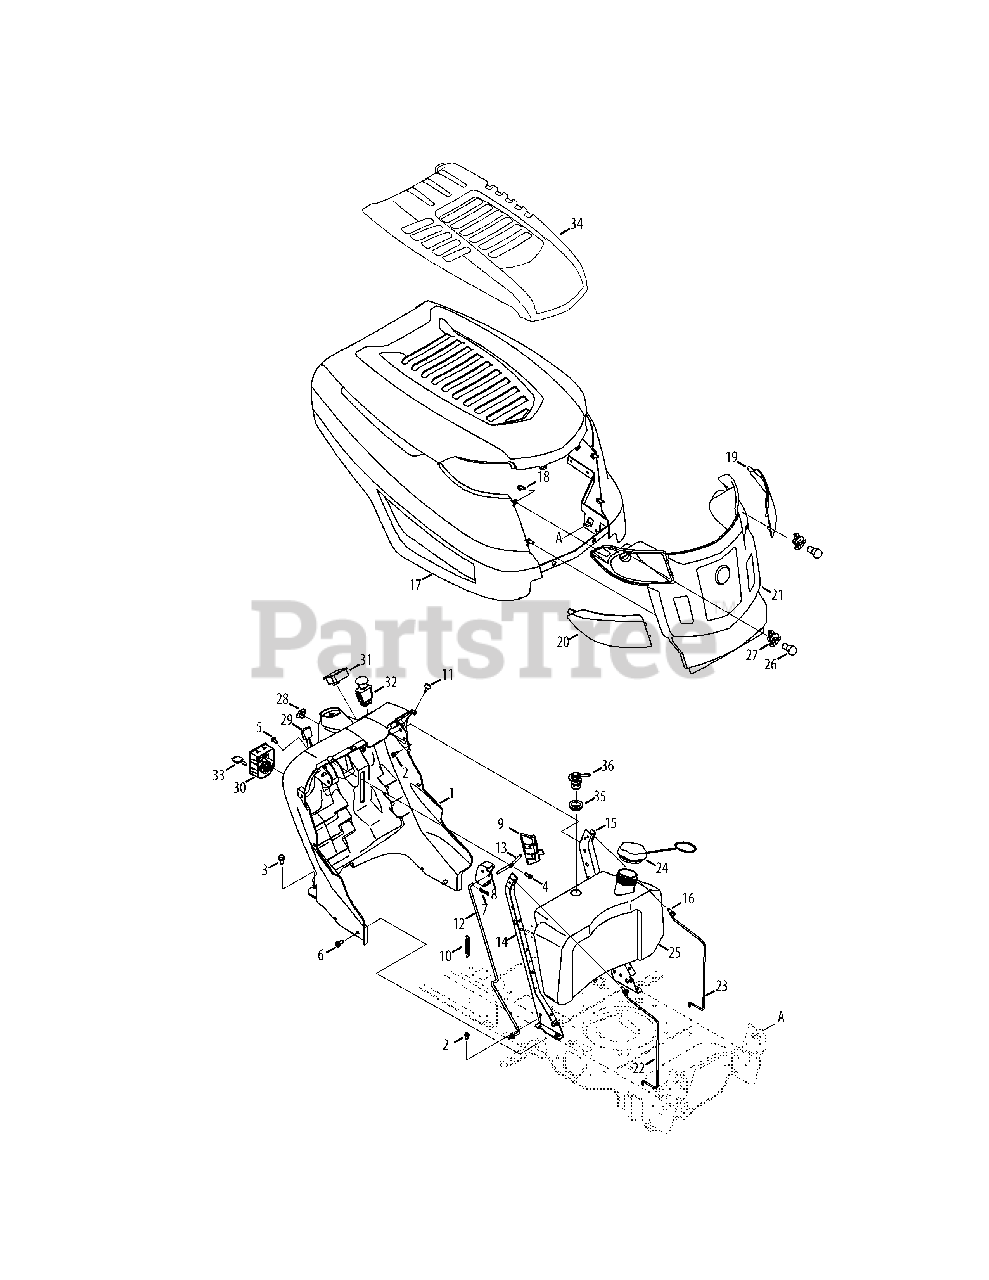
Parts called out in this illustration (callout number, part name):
1	Dash Assembly
2	Taptite Screw ,1/4-20:0.500
3	Taptite Screw, 5/16-18:0.500
4	Hi-Lo Screw, 1/4-15:0.750
5	Screw, 1/4-14:0.625
6	Taptite Screw ,5/16-18:0.750
7	Bow Tie Cotter Pin
8	Dash Lever
9	Cruise Cover
10	Extension Spring, .500 DIA x 2.733 LG
12	Control Rod
14	RH Support Plate
15	LH Support Plate
16	Taptite Screw, 1/4-20:0.750
17	Hood Assembly
18	Screw, 1/4 DIA:.750
22	LH Tank Support Rod
23	RH Tank Support Rod
24	Fuel Cap, EPA
25	Fuel Tank, w/ rollover valve
27	Lamp Socket
28	Choke Plug
29	Throttle/Choke Cable
30	Key Switch Module
31	Hour Meter
32	Electric PTO Switch
34	Hood Scoop
35	Grommet, Rubber, 23.0 ID
36	Valve, Rollover Grommet
